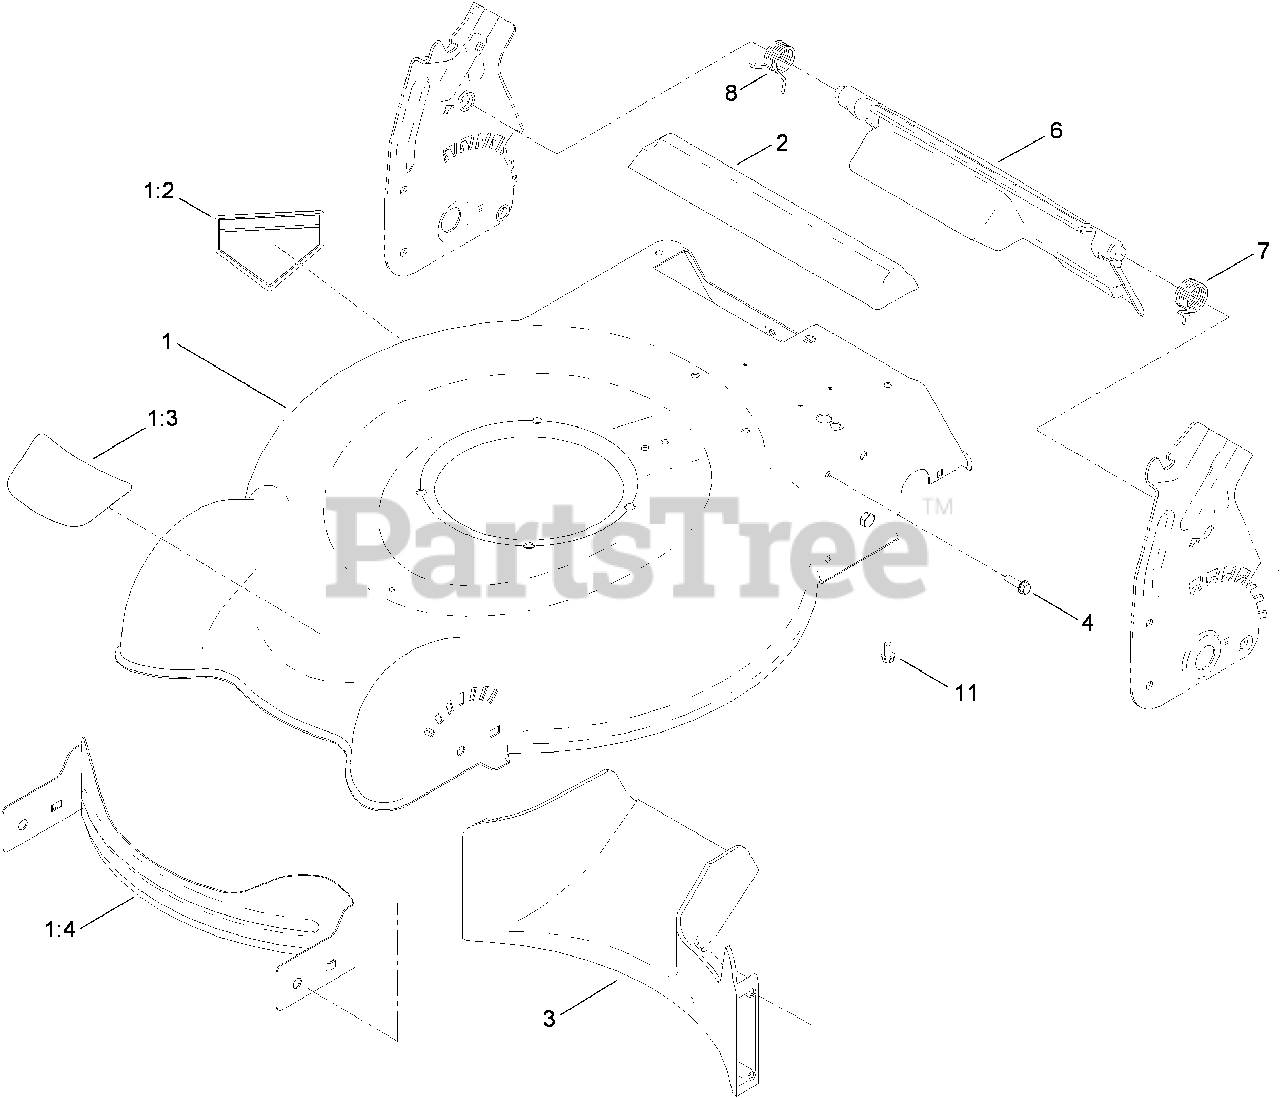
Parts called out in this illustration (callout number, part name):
1	HOUSING ASM
1:2	DECAL-DANGER
1:4	BAFFLE-FRONT
2	CHUTE-REAR
3	BAFFLE-REAR
4	SCREW-HWH
6	REAR DEFLECTOR ASM
7	SPRING-TORSION, LH
8	SPRING-TORSION, RH
11	SCREW-PLASTITE
